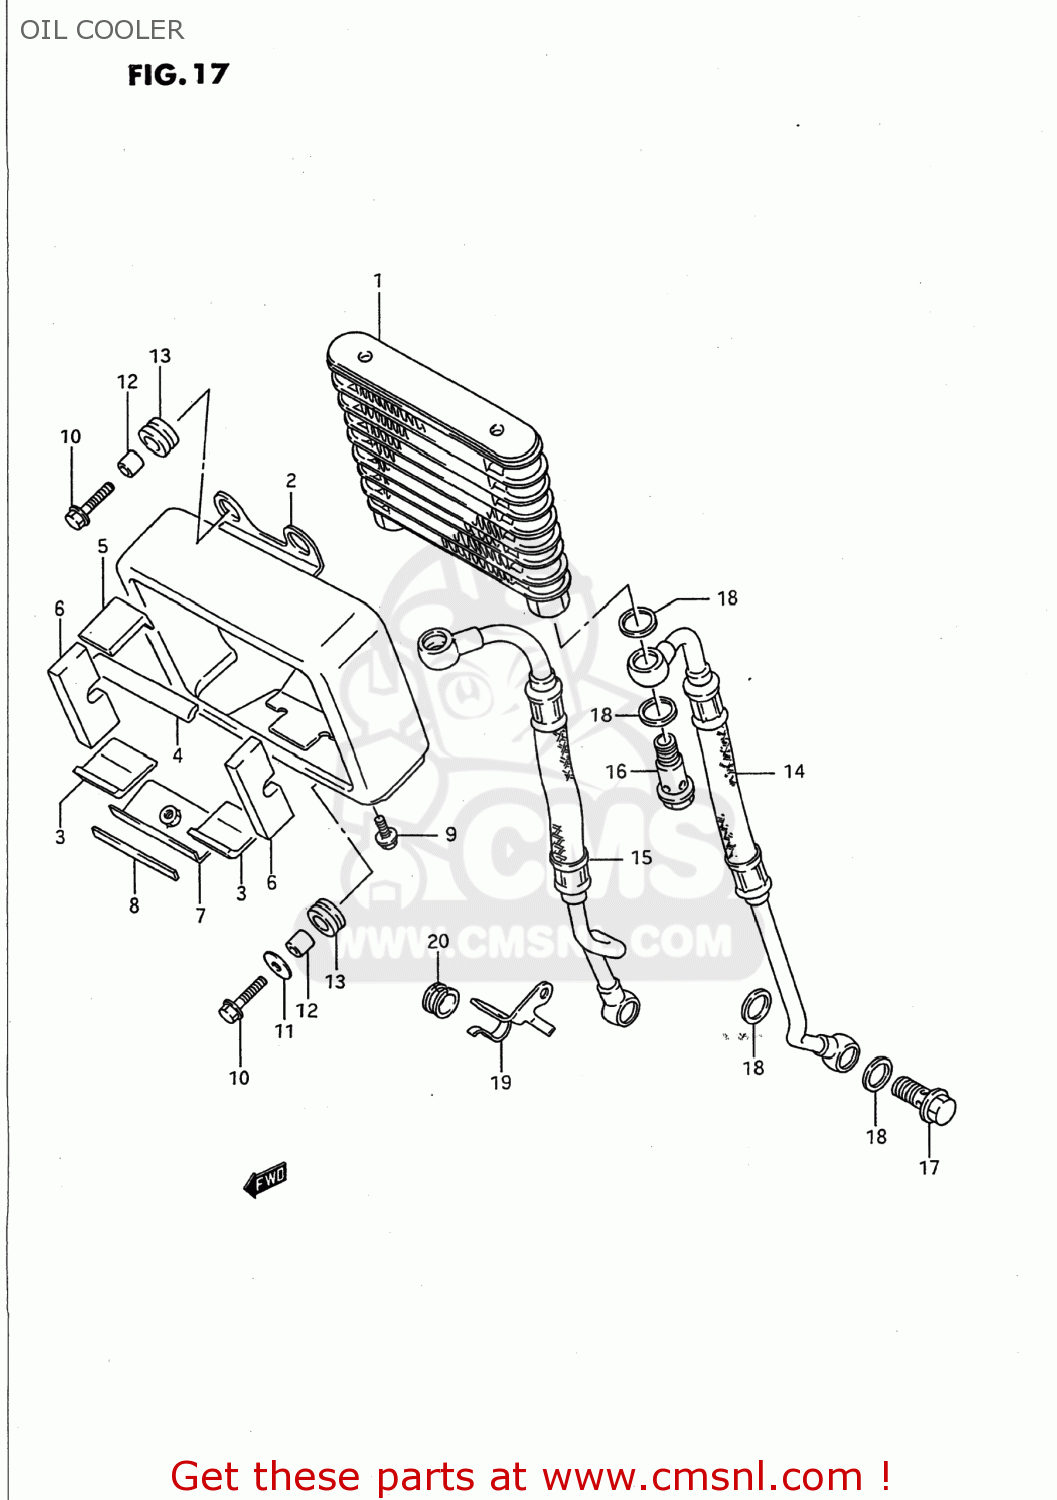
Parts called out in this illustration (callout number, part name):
1	COOLER ASSY,OIL
2	COVER,OIL COOLER
3	CUSHION,COOLER COVER LWR
4	CUSHION,CLLOER COVER UPR NO2
5	CUSHION,COOLER COVER UPR NO1
6	CUSHION,COOLER COVER SIDE
7	BRACKET,OIL COOLER
8	CUSHION,OIL COOLER BRACKET
9	BOLT
10	BOLT
11	WASHER(6.5X20X1.6)
12	SPACER (6.8X10X10)
13	CUSHION
14	HOSE,OIL
15	HOSE,OIL
16	BOLT UNION
17	BOLT UNION
18	GASKET(14X20X1.5) (NAS)
19	CLAMP,OIL COOLER HOSE,R
20	CUSHION
